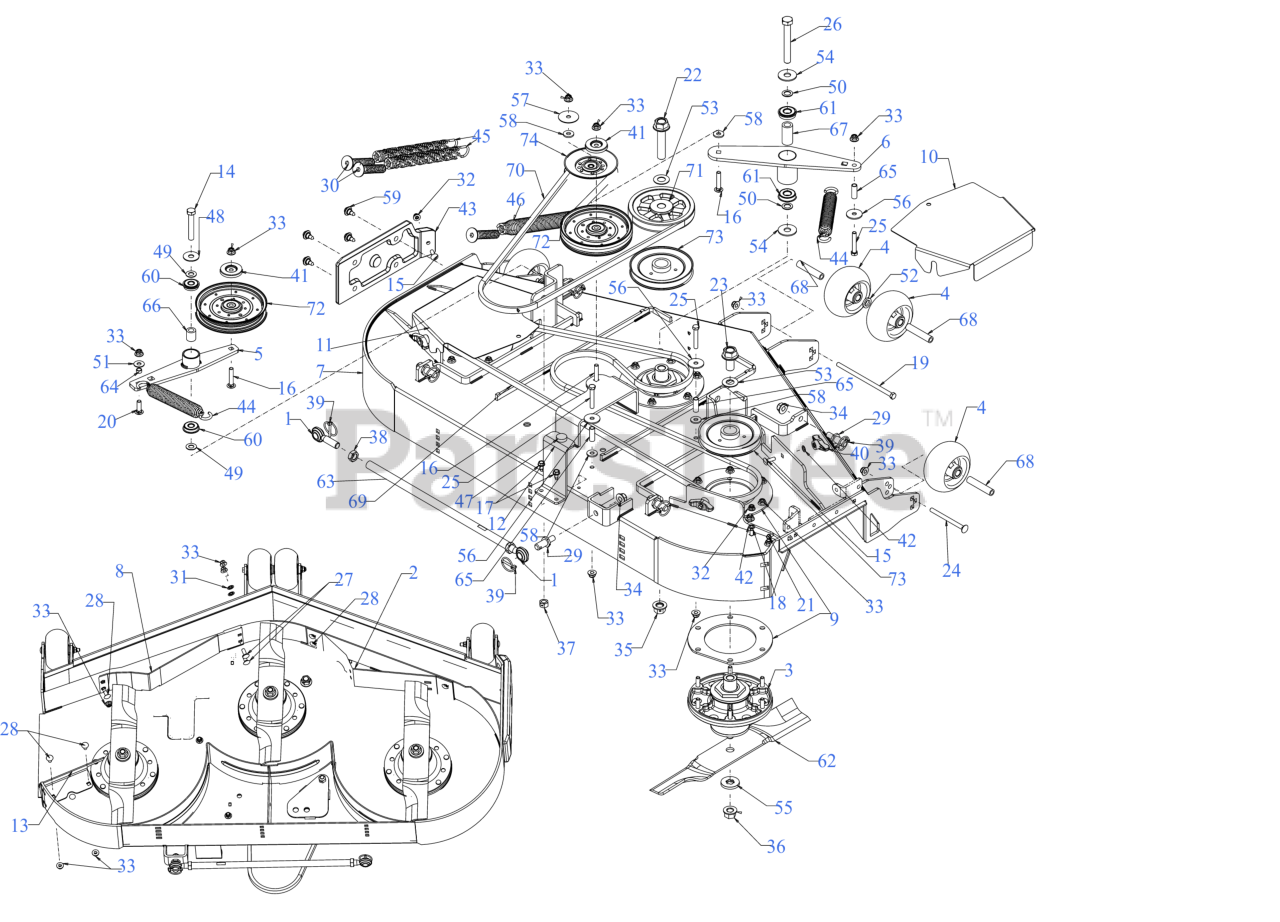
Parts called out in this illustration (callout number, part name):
1	MALE ROD END
2	BAFFLE - 54" ADJ
3	SPINDLE ASSEMBLY
4	5" DIA DECK WHEEL COMPLETE
4	WHEEL BUSHING
5	IDLER BRACKET
6	IDLER BRACKET
7	54" FAB DECK SHELL
9	SPINDLE SUPPORT BRACKET TOP/BTM
10	BELT COVER (RH)
11	BELT COVER (LH)
12	DECK STOP BRACKET
13	CHUTE BAFFLE
14	SCREW-HEX 1/2-13 x 3.00
15	CARRIAGE BOLT 5/16-18 x 1.00
16	CARRIAGE BOLT 3/8-16 x 2
17	SCREW 5/16-18 x .750
18	CARRIAGE BOLT 5/16-18 x .75
19	SCREW 3/8-16 x 7.25 GR5
20	CARRIAGE BOLT 3/8-16 X1.25 GR5
21	SCREW 1/4-20 X.500
22	CAP SCREW-HHFLG 3/4-10 X 3.50 GR8
23	CAP SCREW-HHFLG 3/4-10 X 1.50 GR8
24	CARRIAGE BOLT 3/8-16 x 4.25 GR5
25	SCREW 3/8-16 x 2.25 GR5
26	SCREW 5/8-18X4.5 GR5
27	CARRIAGE BOLT 3/8-16 x 1.00 GR5
28	CARRIAGE BOLT 3/8-16 x .75
30	SPRING INSERT SCREW
32	FLANGE LOCK NUT 5/16-18
36	FLANGE NUT - 5/8-18 GDE 8
37	HEX NUT CTR LK 1/2-13
38	HEX JAM NUT 5/8-18
39	LYNCH PIN .1875
40	WING KNOB 5/16-18
41	PULLEY CAP
43	DECK SKID PLATE (LH)
44	SPRING 1.25" DIA x 8.5" LONG
45	EXTENTION SPRING 1.20 x 11.35
46	EXTENSION SPRING 1.44 OD x 11.36
47	RUBBER BUMPER 1.000 x .313
48	FLAT WASHER
49	FLAT WASHER .510X.995
50	FLAT WASHER
51	WASHER-.395 x 1.0 x .62
52	FLAT WASHER .632X1.00X.16
53	FLAT WASHER
54	FLAT WASHER 0.635xX1.755x0.110
55	FLAT WASHER - SPECIAL
56	FLAT WASHER .406X1.5X11
57	HUB CAP WASHER .406 x 1.92 x .060
58	FLAT WASHER .406ID X1.0 OD
59	SHOULDER SCREW .43X.29X5/16-18 TT
60	ROLLER BEARING .5X1.37X.44
61	BALL BEARING W/RET
62	19" BLADE (HI LIFT)
62	Cub Cadet 54" HI LIFT BLADE SET
62	LOW-LIFT 19"BLADE (54"DECK)
62	BLADE- HI LIFT 19.0 XTREME
62	BLADE-19"MULCH 54"
62	19" XTREME BLADE
63	TUBE .565 X .750 X 18.75"LG
66	SPACER 0.51 x 0.88 x 1.00
67	SPACER 0.63 x 1.00 x 2.01
68	WHEEL SPACER .38ID x 3.04LG
69	BELT-B SECTION 119.45"
70	BELT SEC B x 90.30
71	PULLEY-6.96 OD x .750 ID
72	IDLER PULLEY
73	SPINDLE PULLEY 6"
74	IDLER PULLEY 5.06 OD
